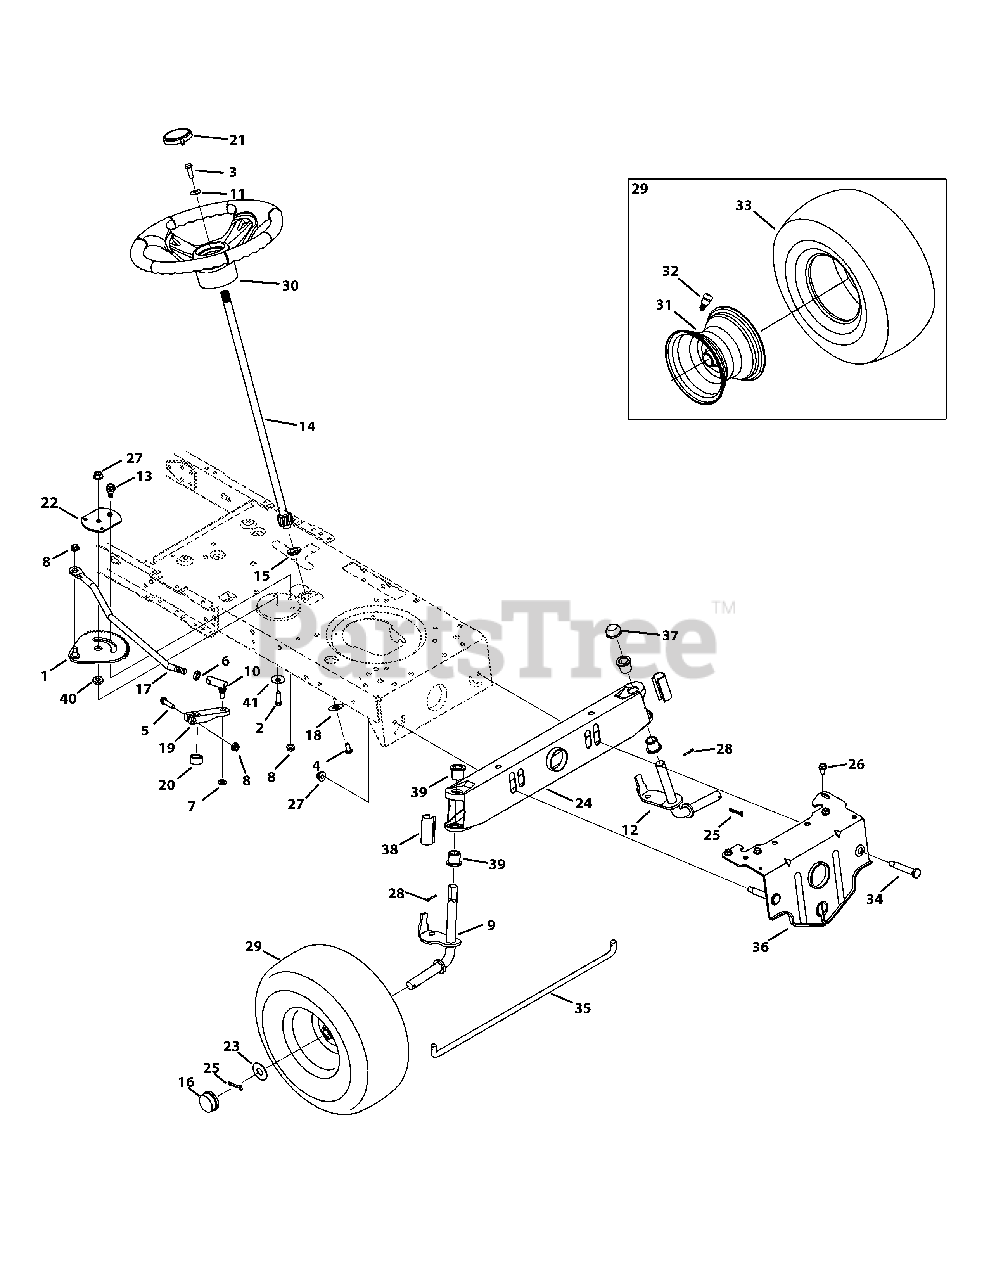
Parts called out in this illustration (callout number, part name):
1	Front Steering Gear Assembly
2	Hex Screw, 3/8-16 x 1.00
3	Hex Screw, 5/16-18 x 1.00, Lock
4	Machine Screw, 5/16-18 x .750
5	Hex Screw, 5/16-18 x 1.75
6	Jam Nut, 7/16-20
7	Jamlock Nut, 3/8-24
8	Flangelock Nut, 5/16-18
9	Front RH Axle
10	Ball Joint, 7/16-20
11	Bell Washer, .340 x .872 x .060
12	Front LH Axle
13	Shoulder Bolt, 5/16-18 x .435 x .350
14	Steering Shaft, 5/8
15	Flange Bearing, 5/8
16	Hub Cap
17	Steering Link
18	Cap, 1.25 x .16
19	Steering Block
20	Spacer, .71 x .125 x .56
21	Sprig Cap
22	Stabilizer Plate
23	Flat Washer, .781 x 1.590
24	Pivot Axle
25	Cotter Pin, 5/32 x 1.25
26	Screw, 5/16-18 x .750
27	Flangelock Nut, 3/8-16
28	Cotter Pin, .125 x .75
29	Wheel Assembly, 42"
30	Steering Wheel
31	Rim Asm, 6.0 x 4.5
32	Valve, tubeless Air
33	Tire, 15 X 6 X 6 Rd Shldr, 42"
34	Shoulder Bolt, 3/8-16 x .500 x 2.38
35	Fixed Rod
36	Pivot Bar Bracket
37	Push Cap, 3/4
38	Standard Axle Cap
39	Flange Bearing, .760 x .941 x 1.0
40	Spacer, .38 ID x .854 OD x .20
41	Bell Washer, .390 x 1.13 x .062
